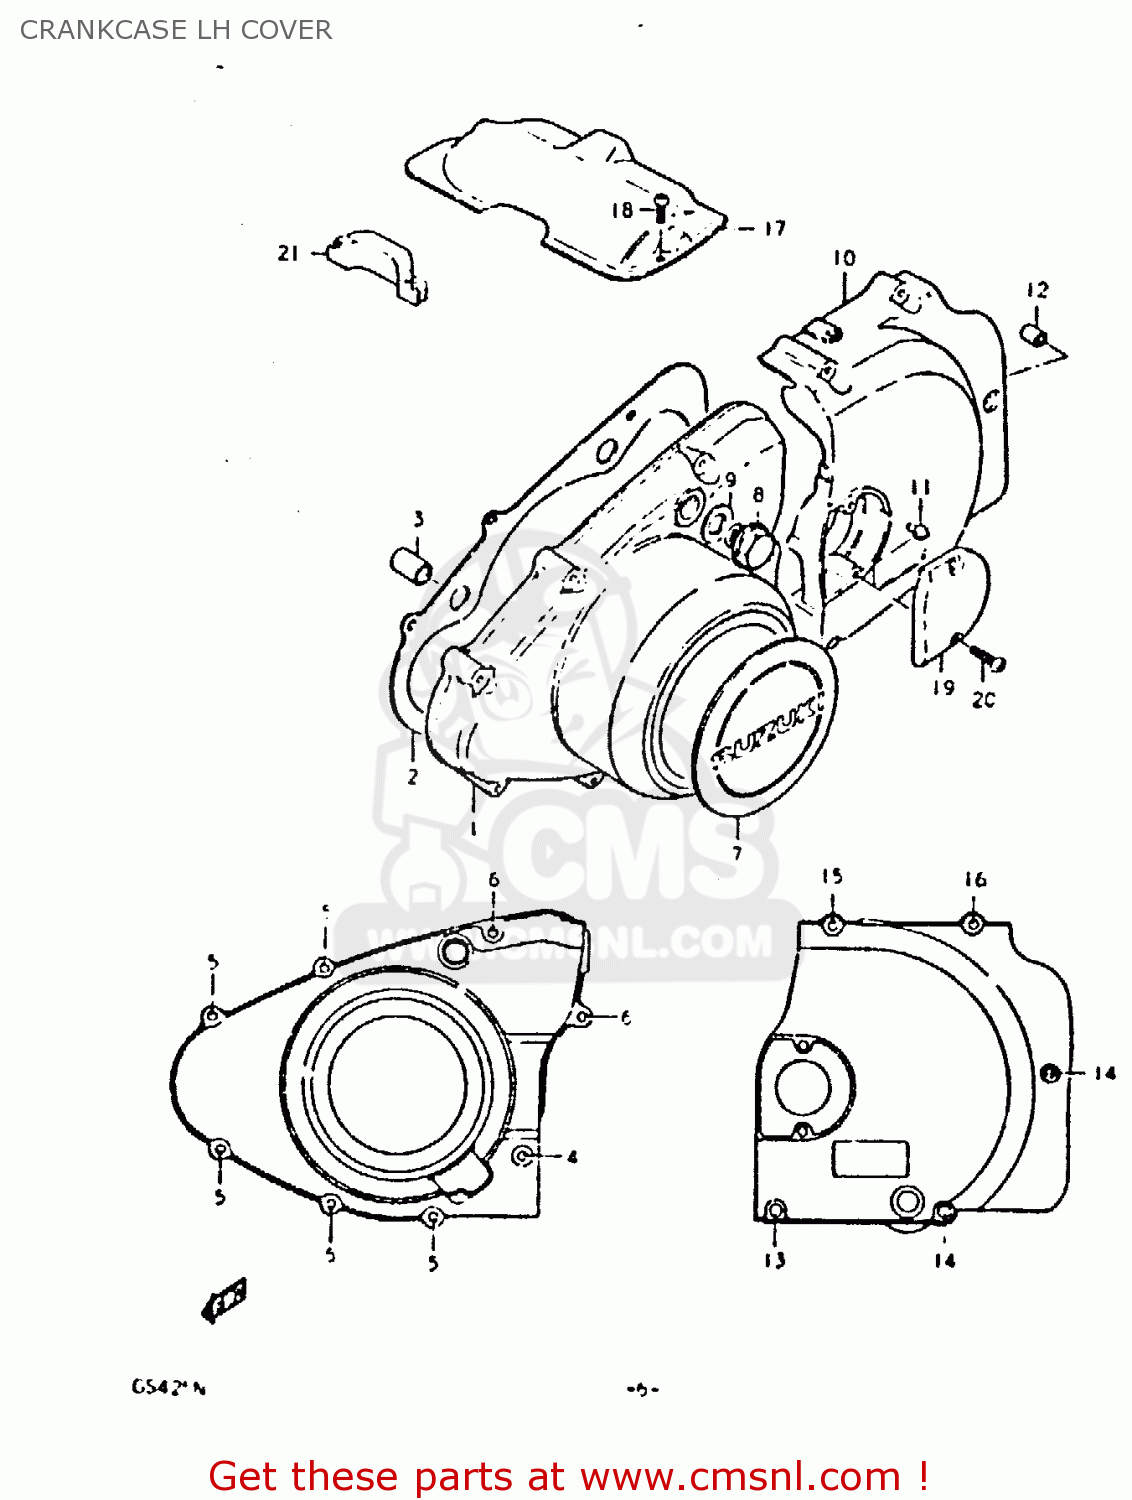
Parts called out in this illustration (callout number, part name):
1	COVER
2	GASKET,MAGNETO COVER (MCA)
3	PIN
4	SCREW
5	SCREW (6X35)
6	SCREW
7	EMBLEM
8	PLUG (14X12)
9	GASKET(14X19.2X2) (NAS)
10	COVER,ENGINE SPROCKET
11	NIPPLE
12	PIN
13	SCREW 6X65
14	SCREW 6X60
15	SCREW
16	SCREW
17	COVER,STARTER MOTOR
18	SCREW
19	CAP,CLUTCH RELEASE ADJUST
20	SCREW
21	GROMMET,STARTING MOTOR
